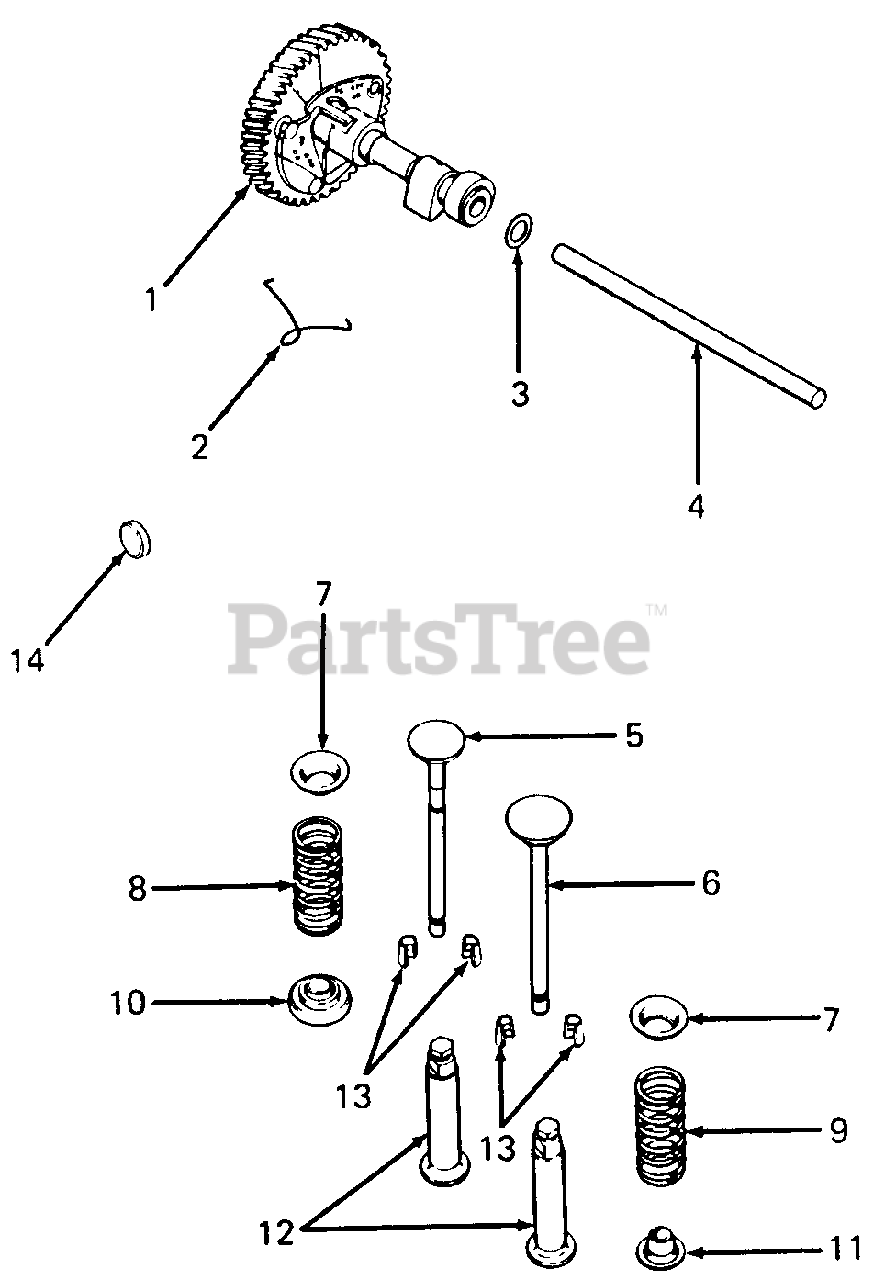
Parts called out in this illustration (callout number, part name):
1	Camshaft Assembly
2	Spring, Actuating
3	Spacer, .005
4	Pin, Camshaft
5	Valve, Exhaust
6	Valve, Intake
7	Retainer, Upper Spring
8	Spring, Exhaust Valve
9	Spring, Intake Valve
10	Rotator
11	Retainer, Spring
13	Kit, Retainer
14	Plug, Cup
